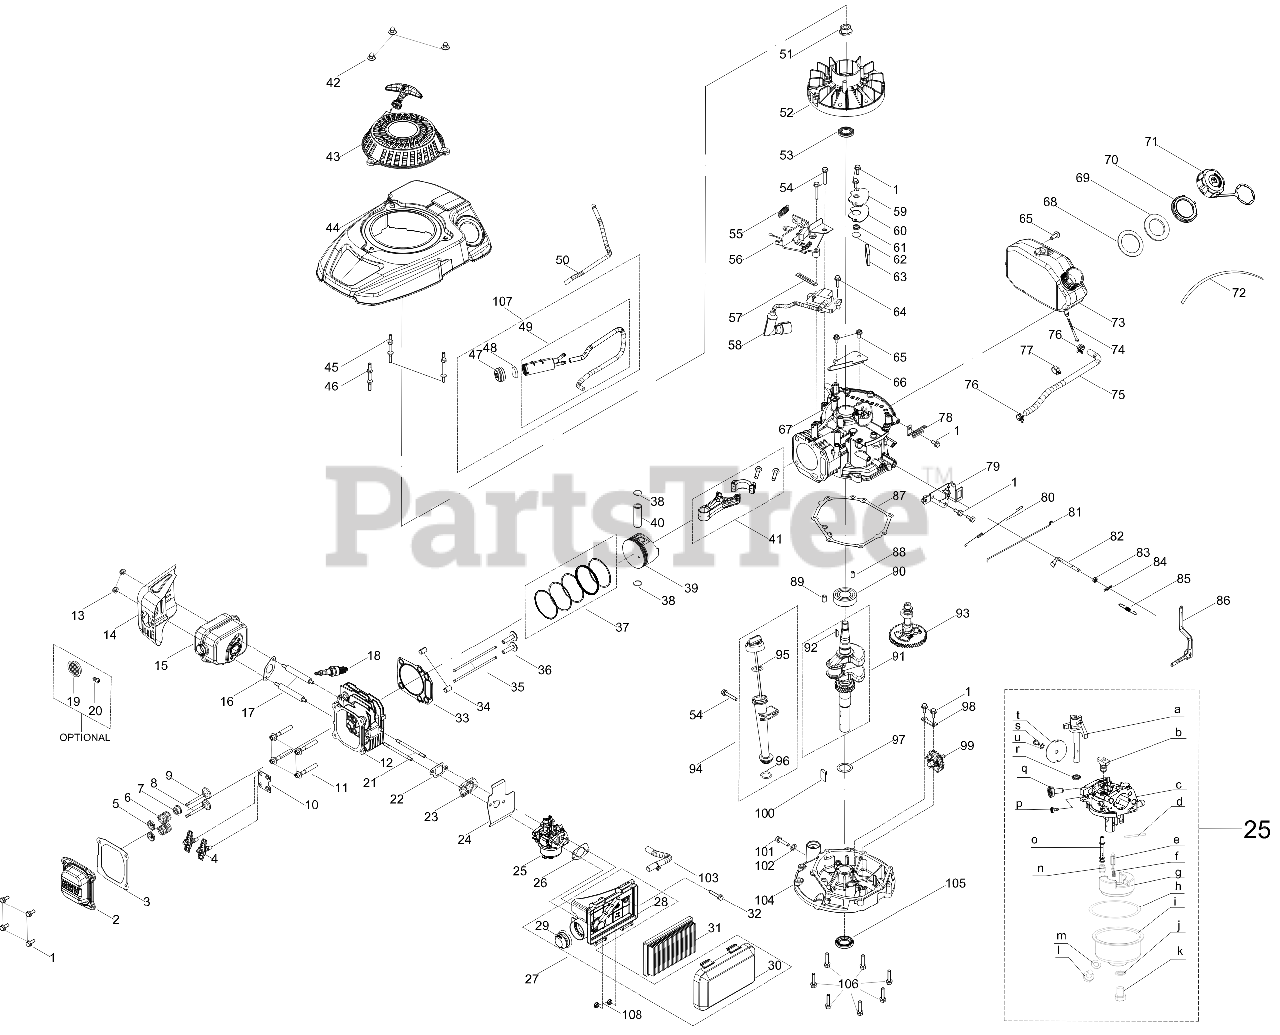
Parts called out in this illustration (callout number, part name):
1	BOLT M6-1 x 14 GR8.8
2	VALVE COVER
3	VALVE COVER GASKET
4	ROCKER ARM ASSEMBLY
5	VALVE SPRING RETAINER
6	VALVE SPRING
7	INTAKE VALVE SEAL
8	EXHAUST VALVE
9	INTAKE VALVE
10	PUSH ROD GUIDE
11	BOLT-M8 x 54
12	CYLINDER HEAD
13	HEX NUT
14	MUFFLER SHIELD
15	MUFFLER
16	MUFFLER GASKET
17	STUD M6-1 x 95
18	SPARK PLUG
19	SPARK ARRESTOR
20	SCREW M3.5 x 9.5
21	CARBURETOR STUD-M6 x 87
22	CARBURETOR GASKET
23	CARBURETOR INSULATOR
24	CARBURETOR GASKET
25	CARBURETOR ASSEMBLY HY-1X65BA
26	AIR FILTER BASE GASKET
27	AIR FILTER ASSEMBLY
28	AIR FILTER BASE
29	PRIMER BULB (NON-VENTED)
30	AIR FILTER COVER
31	AIR FILTER
31	Genuine Factory Parts AIR FILTER
32	BOLT-M6-1 x 30 GR8.8
33	CYLINDER HEAD GASKET
34	DOWEL PIN
35	PUSH ROD
36	TAPPET
37	PISTON RING SET
38	SNAP RING-PISTON PIN
39	PISTON
40	PISTON PIN
41	CONNECTING ROD ASSEMBLY
42	ACORN NUT
43	RECOIL STARTER ASSEMBLY
44	BLOWER HOUSING
45	STARTER/SHROUD REAR STUD
46	STARTER/SHROUD FRONT STUD
47	CARBON CANISTER FILTER CAP
48	CARBON CANISTER FILTER
49	CARBON CANISTER
50	CARBON CANISTER PURGE HOSE
51	FLYWHEEL NUT
52	FLYWHEEL
53	CRANKSHAFT SEAL
54	BOLT M6-1 x 35 GR8.8
55	ENGINE BRAKE SPRING
56	ENGINE BRAKE ASSEMBLY
57	FLEXIBLE CLAMP
58	IGNITION COIL
59	BREATHER COVER PLATE
60	BREATHER GASKET
61	BREATHER VALVE SPRING
62	BREATHER VALVE
63	BREATHER SCREEN
64	BOLT M6-1 x 20 GR8.8
65	BOLT M6-1 x 12 GR8.8
66	AIR VANE COVER PLATE
67	CRANKCASE
68	FUEL TANK LOWER GROMMET
69	FUEL TANK UPPER GROMMET
70	FUEL TANK NUT
71	FUEL CAP ASSEMBLY
72	CABLE TIE - 3 x 150
73	FUEL TANK
74	FUEL FILTER
74	Genuine Factory Parts FUEL FILTER
75	FUEL HOSE
76	HOSE CLAMP
77	FUEL LINE SUPPORT CLAMP
78	FLEXIBLE CLAMP
79	COMPONENT BRACKET
80	THROTTLE LINKAGE SPRING
81	THROTTLE LINKAGE
82	GOVERNOR ARM SHAFT
83	GOVERNOR SEAL
84	COTTER PIN
85	GOVERNOR SPRING
86	GOVERNOR ARM ASSEMBLY
87	CRANKCASE COVER GASKET
88	DOWEL PIN
89	DOWEL PIN
90	BEARING
91	CRANKSHAFT ASSEMBLY
92	FLYWHEEL KEY
93	CAMSHAFT ASSEMBLY
94	OIL DIPSTICK ASSEMBLY
95	O-RING
96	O-RING
97	THRUST WASHER
98	GOVERNOR GEAR MOUNTING PLATE
99	GOVERNOR GEAR/SHAFT ASSEMBLY
100	OIL RETURN SEAL
101	OIL DRAIN PLUG
102	WASHER
103	BREATHER HOSE
104	CRANKCASE COVER
105	LOWER CRANKSHAFT SEAL
106	BOLT-M6-1 x 28 GR8.8
107	CARBON CANISTER ASSEMBLY
108	HEX NUT
U	Throttle Plate Lock Washer
